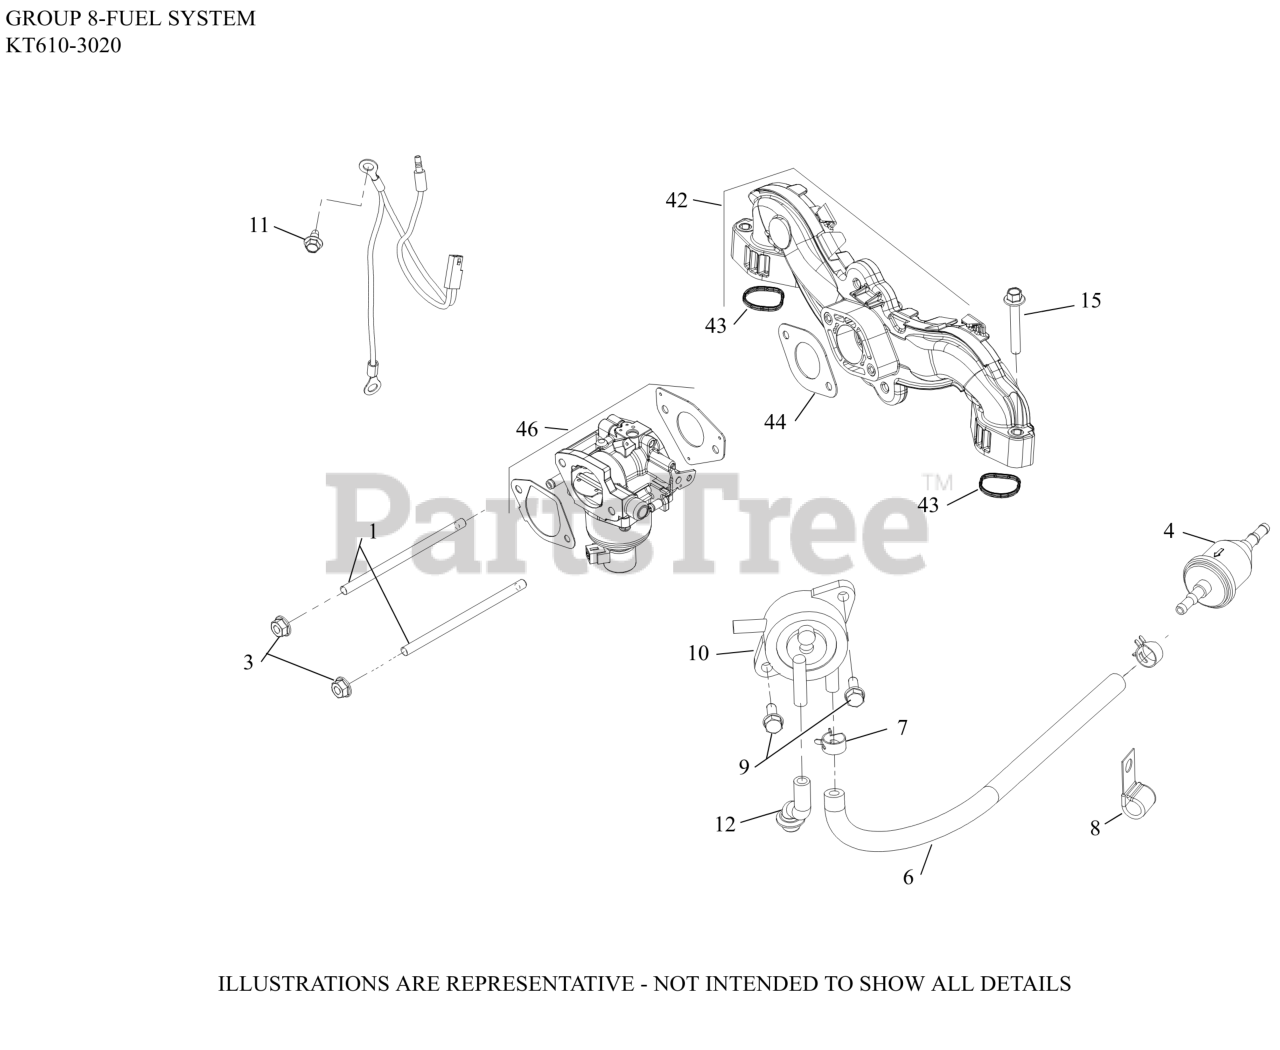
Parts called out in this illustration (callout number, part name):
3	NUT, FLG M6X1.0
4	FILTER,FUEL 51 MICRON (FUEL PUMP)
6	HOSE,LW PERM.FUEL 24.00"-USE 25 111 81-S
7	SPRING CLAMP, HOSE
8	CLIP, CABLE (KM)
9	SCREW, TAP M6X1.7X18
10	PUMP, FUEL (PULSE)-(#2539326S)
11	SCREW, THREAD FORMING
12	HOSE, PULSE PUMP(STEEL COVERS)
15	SCREW, FLG M6X1.0X40
42	INTAKE MANIFOLD W/GASKETS
43	O-RING, INTAKE PORT
44	GASKET, CARBURETOR (PIM, CV)
46	KIT,CARB (NIKKI)
NI	KIT, HIGH ALT (19MM) NIKKI G-TYPE TWIN
NI	KIT, OVERHAUL NIKKI G-TYPE TWIN
NI	KIT, BOWL WITH O-RINGS NIKKI G-TYPE TWIN
NI	KIT, FLOAT AND NEEDLE NIKKI G-TYPE TWIN
NI	KIT,CHOKEREPAIR(SELF REL.)NIKKI G-TYPE T
NI	KIT,THROTTLE SHAFT(19MM)NIKKI G-TYPETWIN
